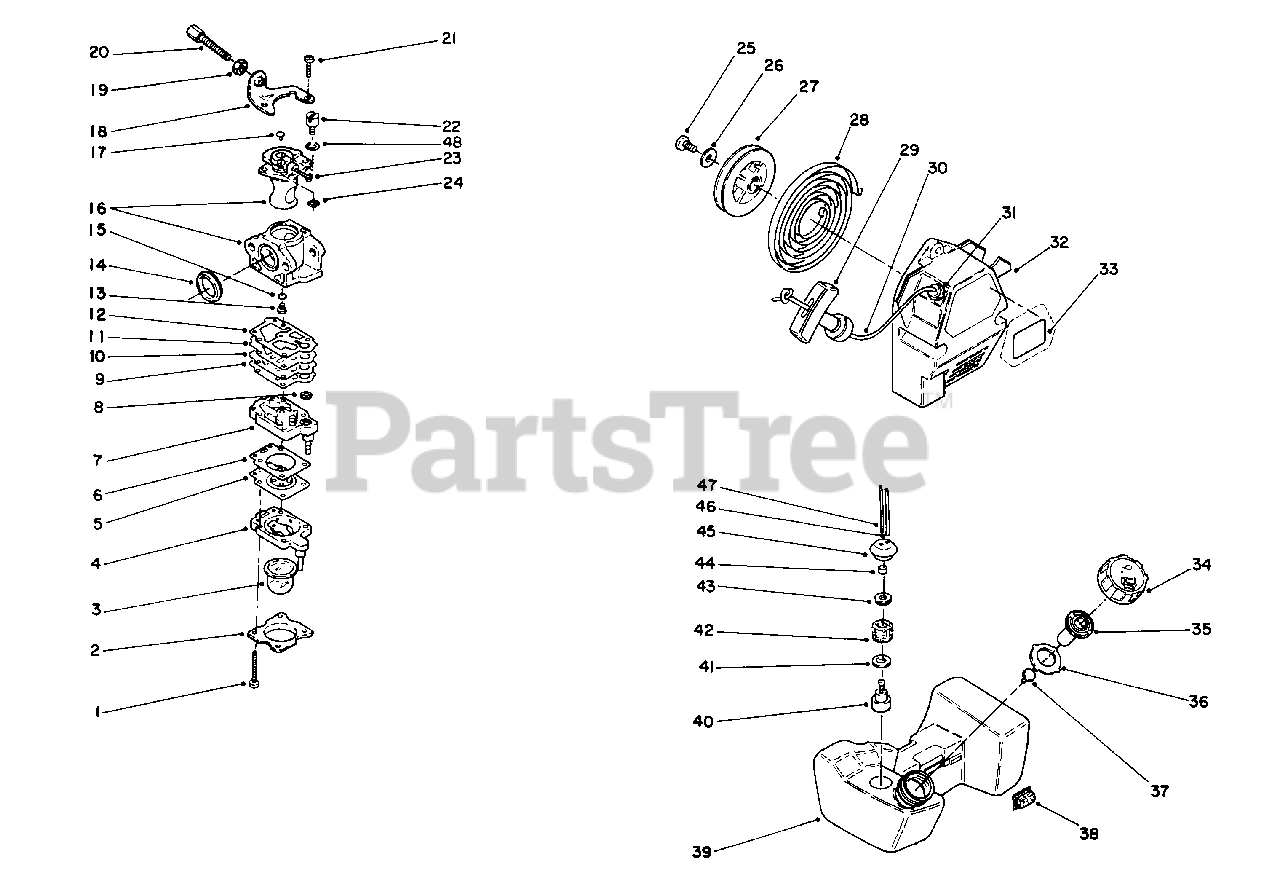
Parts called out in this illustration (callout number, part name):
2	Cover-Primer
3	Bulb-Primer
4	Body-Primer
5	Diaphragm
6	Gasket-Diaphragm
7	Body Assembly (Incl. Ref. #8)
9	Gasket-Pump
11	Diaphragm
12	Gasket-Diaphragm
13	Jet-Main #43
15	"O" Ring-Main Jet
16	Body-Carburetor (Ref.)
19	Nut-Lock
20	Screw-Adjustment
22	Swivel-Cable
23	Valve-Throttle
28	Spring-Recoil
29	Handle-Recoil
30	Rope-Recoil
31	Guide-Rope
32	Case-Recoil
33	Decal-Toro
34	Cap-Fuel
35	Valve-Breather
37	Cap-Valve
39	Tank Assembly-Fuel (Incl. Ref. #34-37 & 40-47)
40	Weight-Filter
41	Washer-Seal
42	Filter-Fuel
43	Washer-Seal
45	Grommet-Fuel Tank
46	Hose-Fuel
47	Tube-Fuel Return
